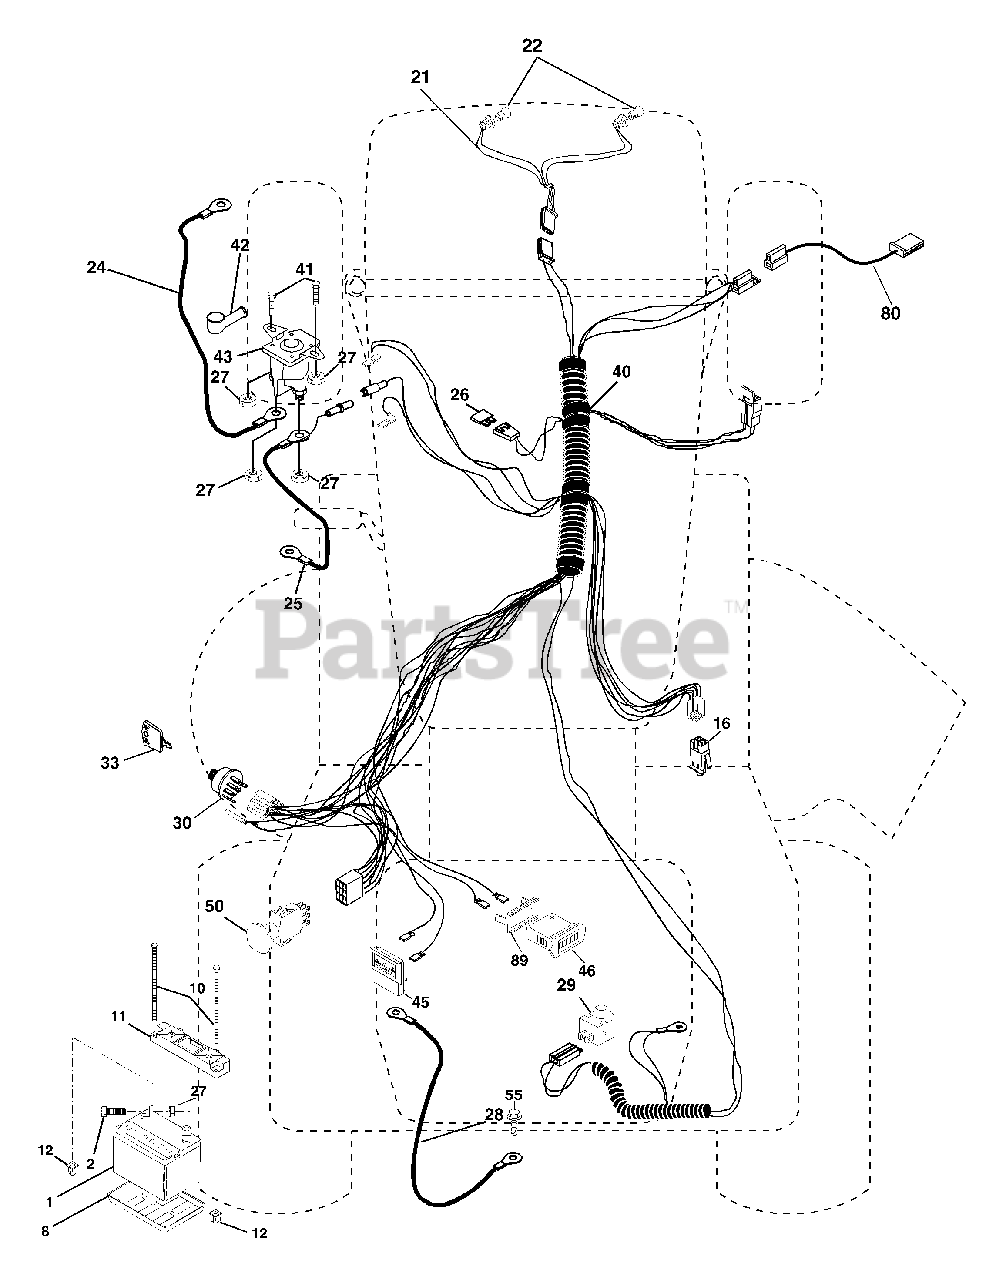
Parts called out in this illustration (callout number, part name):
1	Battery 12 Volt 35 AMP
2	Bolt Hex Hd 1/4-20 unc x 3/4
8	Box Battery
10	Bolt Btr Frt 1/4-20 x 7.5
11	Holddown Battery Front Mount
12	Nut Push Nylon 1/4 Battery Frt.
16	Switch Interlock Push-In
21	Harness Asm Light W/4152j
22	Bulb Light #1156
24	Cable Battery 6 Ga. 22" red w/16 wire
25	Cable Battery 6 Ga. 11" red
27	Nut Keps Hex 1/4-20 unc
28	Cable Ground 6 Ga. 21" black
29	Switch Plunger Nc Gray
30	Switch Ign
33	Key Ign Molded Generic
40	Harness Ign.
41	Bolt Blk Fin Hex 1/4 - 20 x 1/2
42	Cover Terminal Red
43	Solenoid
45	Ammeter Rectangular 15 Amp
46	Meter Hour
50	Switch PTO
55	Screw Thdrol 5/16-18 x 1-1/2 Tyt
